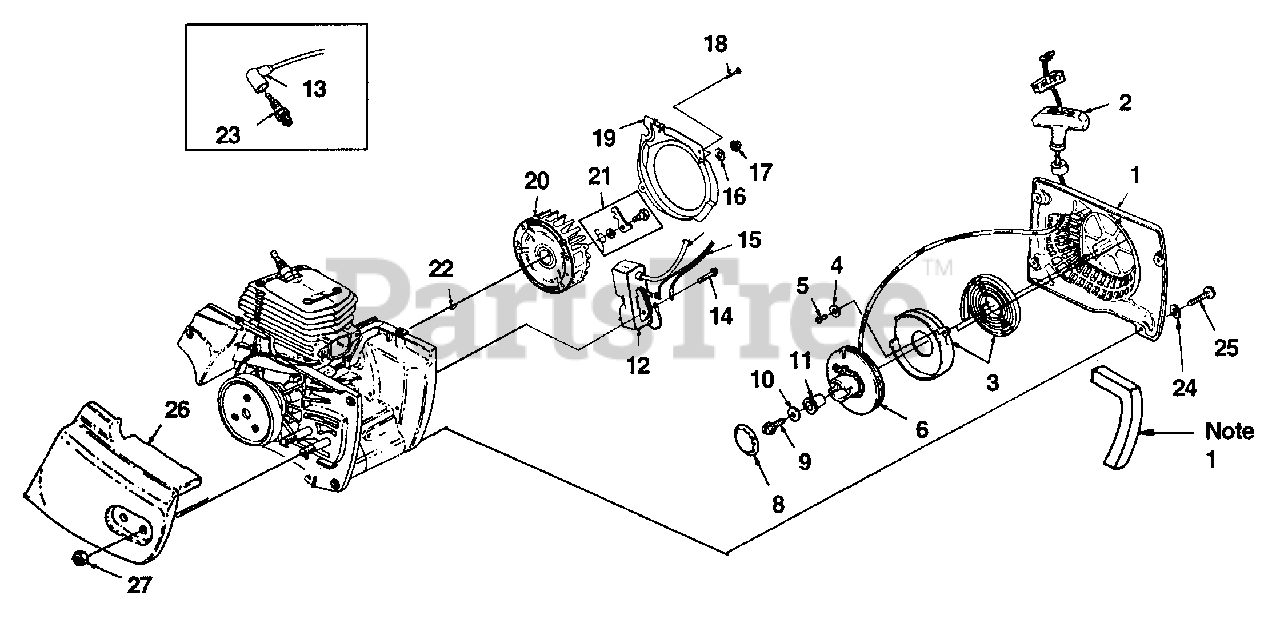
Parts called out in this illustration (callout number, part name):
1	STARTER COMPLETE
2	GRIP-w/Insert
3	SPRING & RETAINER
4	WASHER-Flat (#8)
5	SCREW-Thread Form. (6 x 3/8")
6	PULLEY & ROPE
8	SPRING-Grip
9	SCREW-Plastite (10-14 x 5/8")
10	WASHER-Retaining
11	BUSHING-Starter Post
12	MODULE ASSY.
13	TERMINAL-Spark Plug
14	SCREW-Hex Hd. (10-24 x 7/8")
15	LEAD-Ground w/Grommet
16	WASHER-Flat
17	NUT-Lock Hex (3/8-24)
18	SCREW-Mach. (8-32 x 5/8")
19	SCROLL-Air Guide
20	ROTOR
21	STARTER PAWL KIT
22	KEY-Woodruff
23	SPARK PLUG (RCJ6Y)
24	WASHER-Flat (#10)
25	SCREW-Pan Hd. (10-24 X 5/8")
26	COVER - Drivecase
27	NUT-(3/8-16 x 5/16")
NOTE1	FOAM KIT
